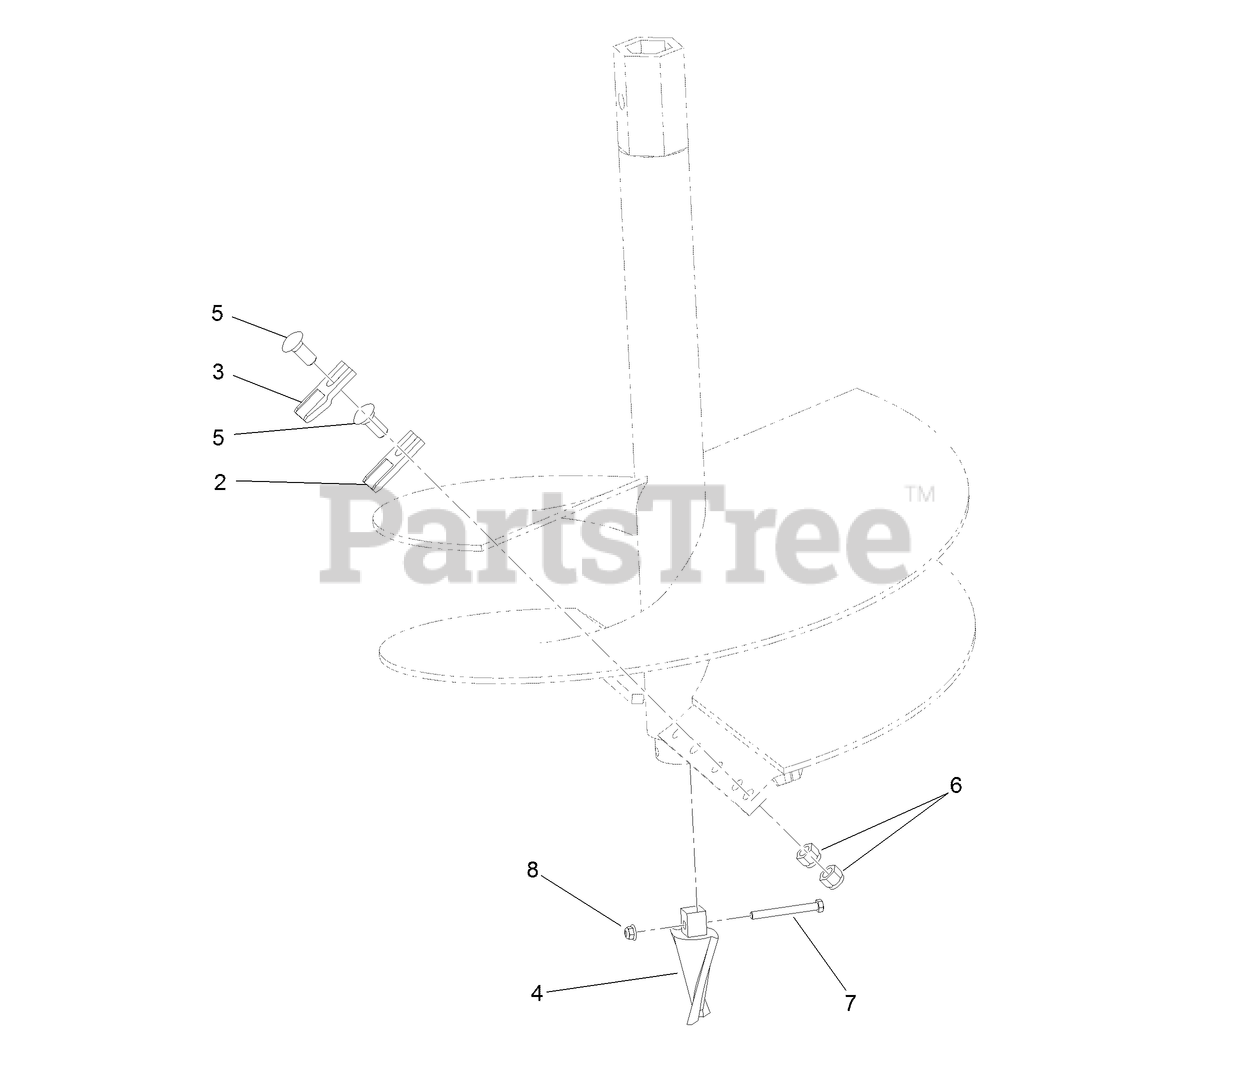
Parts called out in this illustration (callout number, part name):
2	TOOTH-AUGER, WISDOM (INSIDE)
3	TOOTH-AUGER, WISDOM (OUTER)
4	TOOTH-FISHTAIL, STANDARD
5	SCREW-CARRIAGE
6	NUT-LOCK, NI
7	SCREW-HH
8	NUT-HF, NI
